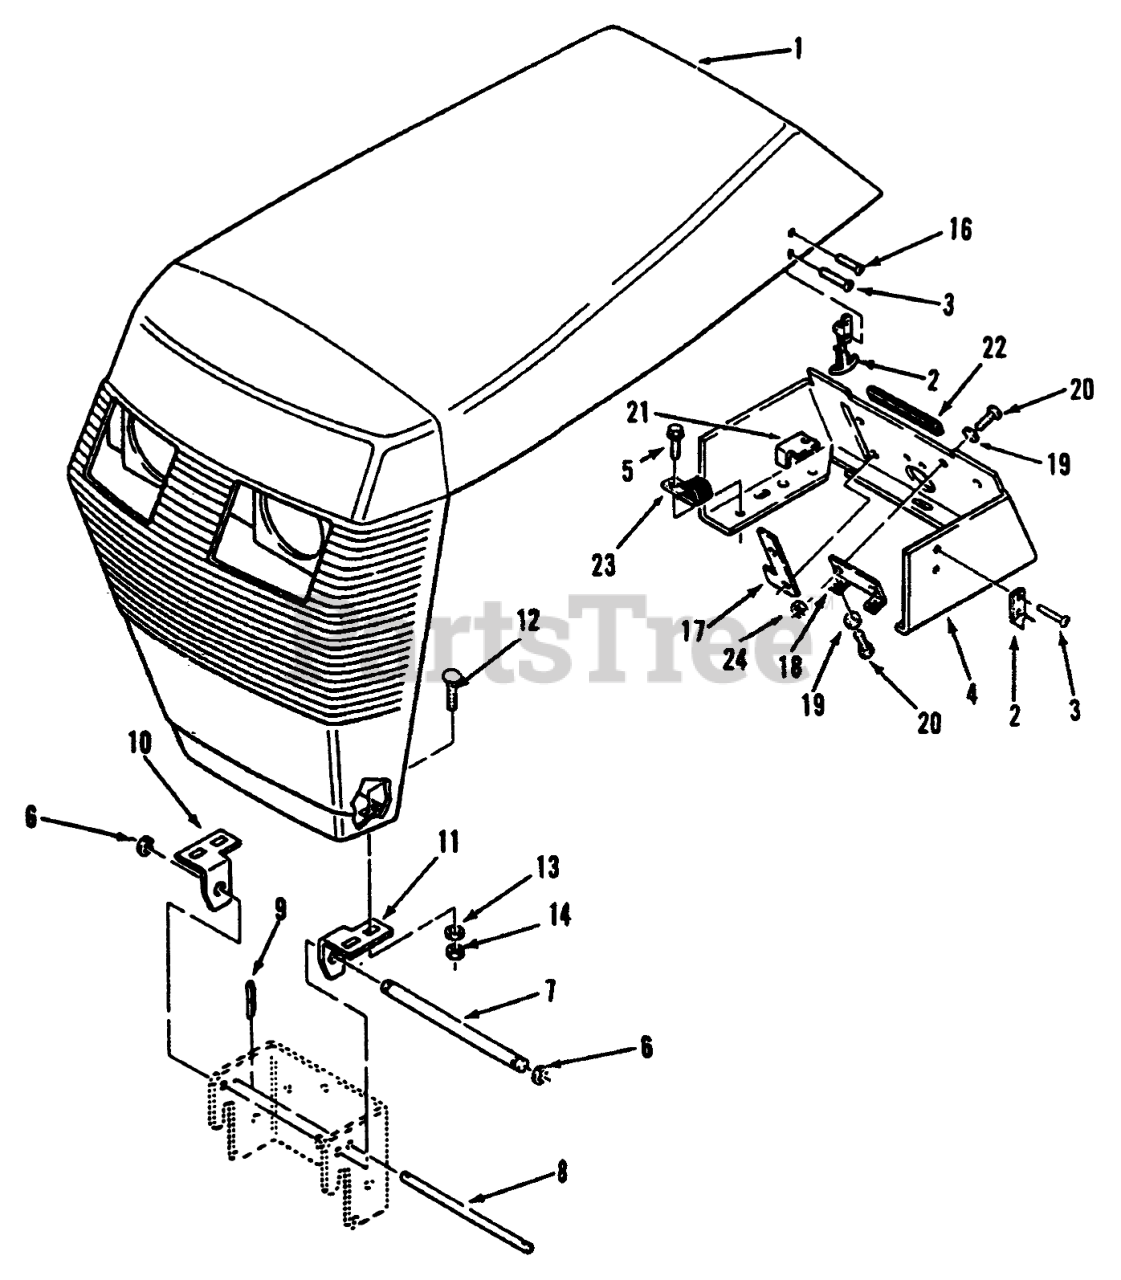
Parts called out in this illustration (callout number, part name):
1	Hood
2	LATCH-FLEX BLK ASS'Y
3	RIVET-POP
4	Console
5	SCREW
6	RING-RETAINING
7	ROD-GRILL PIVOT
8	ROD-HOOD STOP
9	Cotter Pin
10	BRACKET-GRILL, R H
11	BRACKET-GRILL, LH
12	SCREW-CARR
13	WASHER-FLAT
14	NUT-LOCK
16	POPRIVET 1/8X 1/8 BK
17	Washer
18	BRACKET
19	Washer-Lock
20	SCREW
21	STOP-PTO
22	EDGING-CONSOLE
23	J-CLIP
24	NUT-HEX
